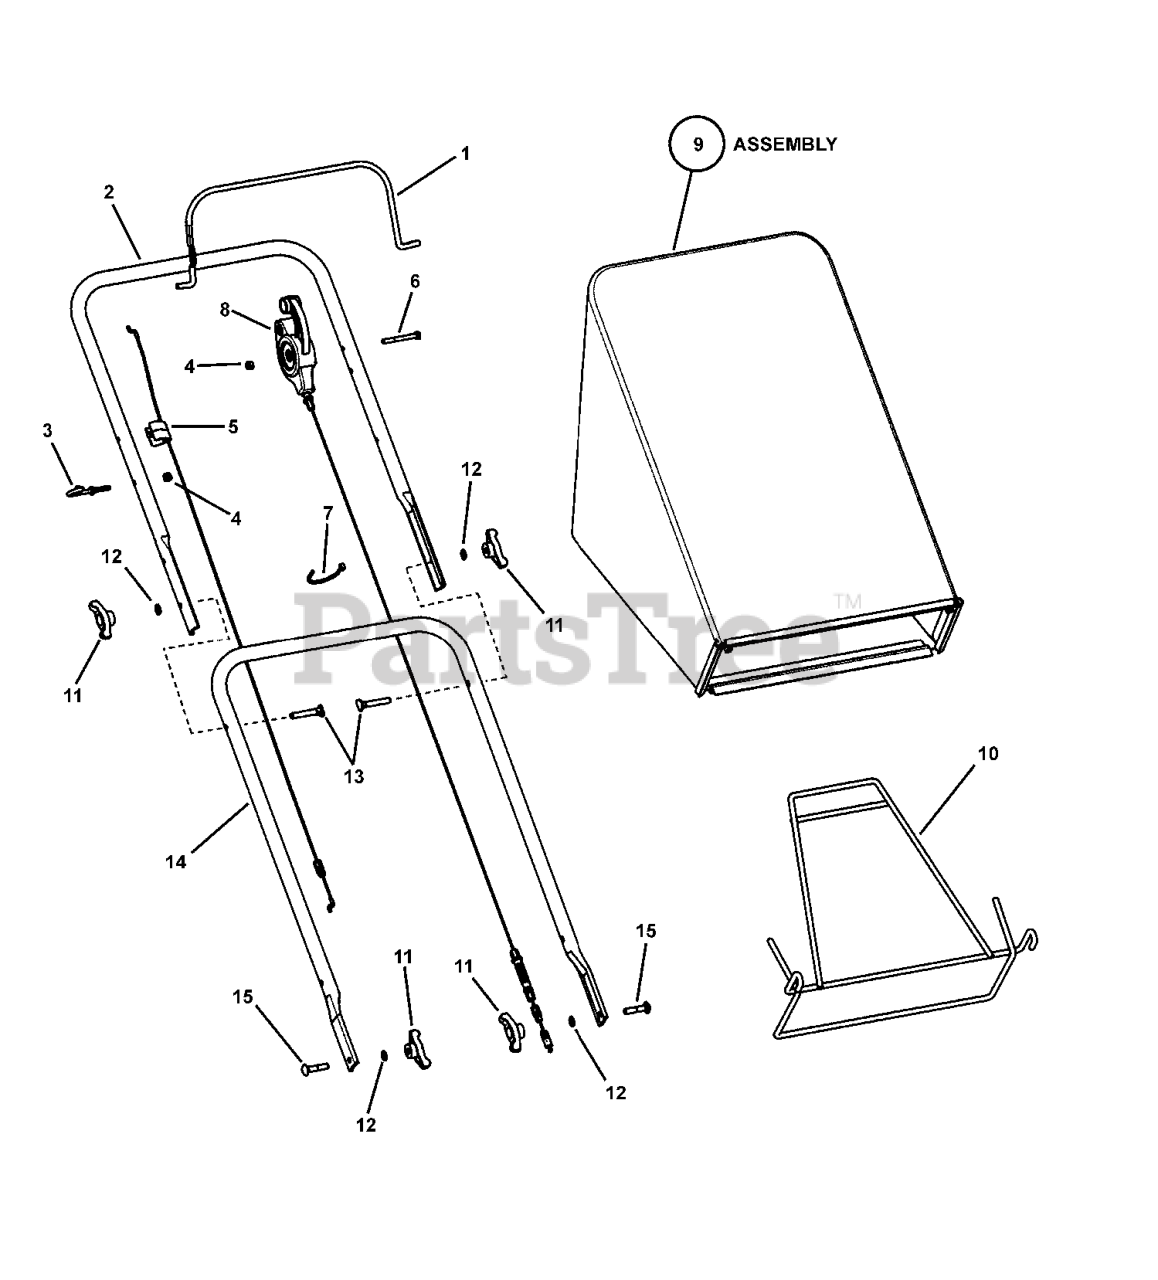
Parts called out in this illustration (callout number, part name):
1	BAIL, OPC Propelled
2	UPPER HANDLE, Propelled
3	GUIDE, Rope - 1/4-20 thread
4	NUT, 1/4-20 Nyloc
5	CABLE, Bail, Std Propelled - 53.50" overall length
5	CABLE, Bail, Hi-Wheel Propelled - 58.00" overall length
6	SCREW, 1/4-20 x 2-1/4 Hex Head Cap, GR 5
7	WIRE TIE, 11 Inch Std Black Nylon
8	CONTROL, Drive, Single Speed Std Wheel
8	CONTROL, Drive, Single Speed Hi-Wheel
9	ASSY, Grass Bag, Cloth - incl. next item below
10	WELDMENT, Frame, Grass Bag
11	KNOB, 5/16-18 Wing - Black
12	WASHER, 5/16" Internal Tooth Lock
13	BOLT, 5/16-18 x 2" Curved Head Square Neck GR 2
14	HANDLE, Lower
15	BOLT, 5/16-18 x 1-1/2" Square Neck Carriage
15	BOLT, 5/16-18 x 1-1/2" Short Square Neck Carriage GR 5
